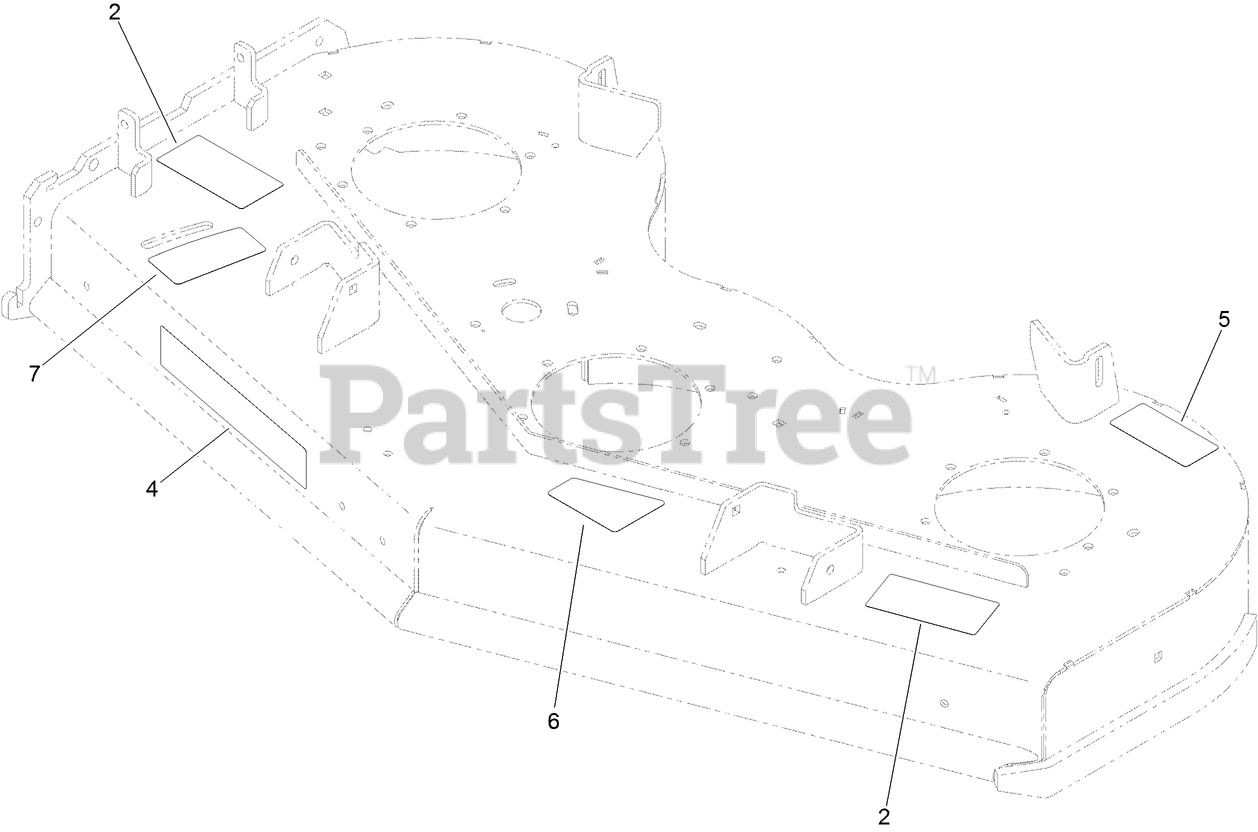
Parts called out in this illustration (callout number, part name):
2	DECAL-DANGER
5	DECAL-TORQUE, BLADE BOLT
6	DECAL-BELT, TENSION (CE)
7	DECAL-ADJUSTMENT, BAFFLE
